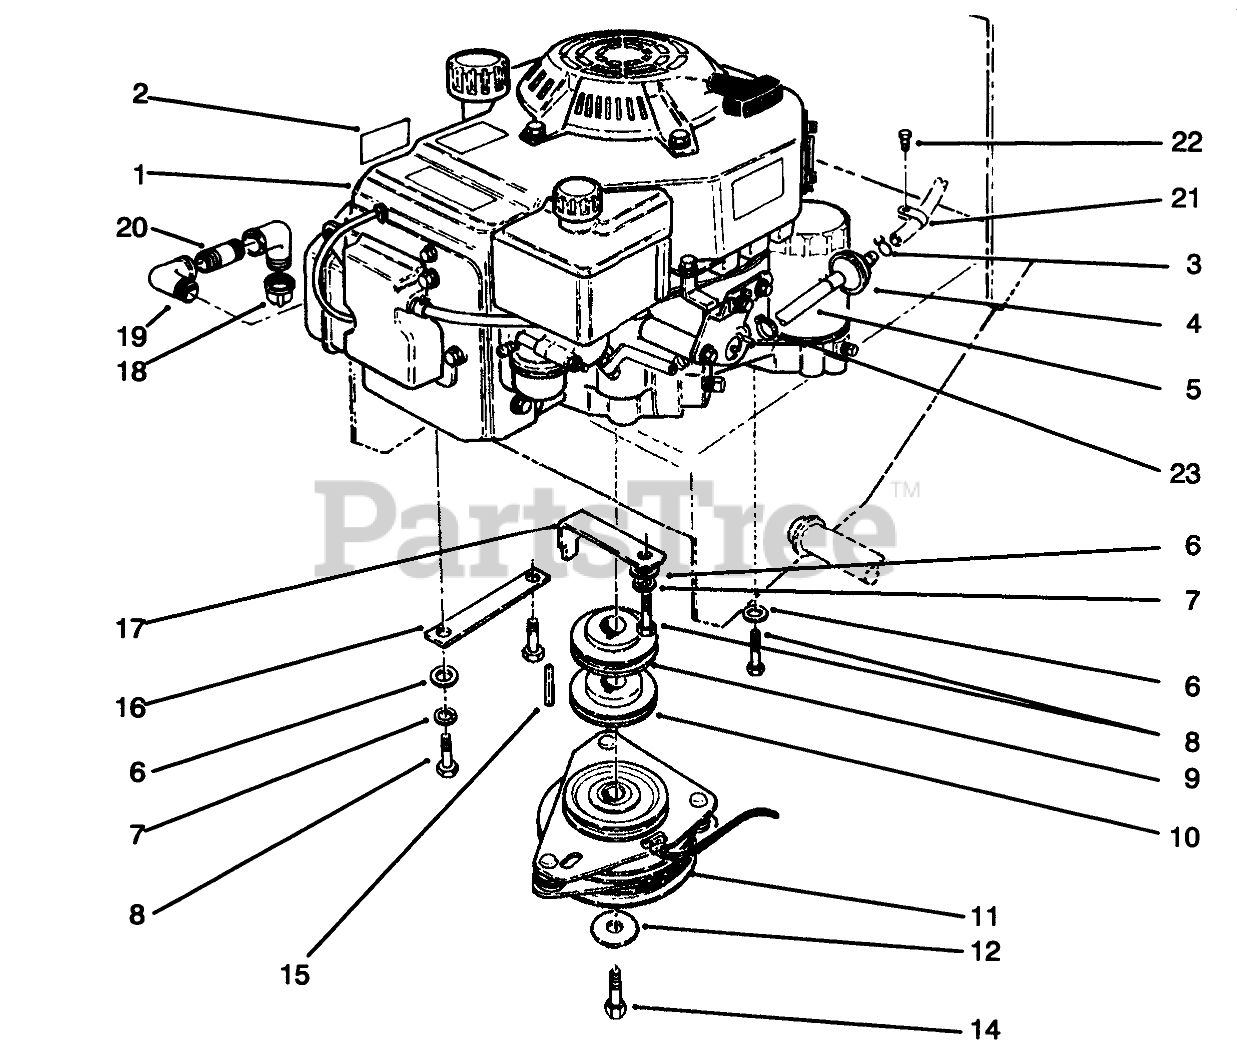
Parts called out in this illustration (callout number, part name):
2	DECAL-SURFACE, HOT
3	CLAMP-HOSE
4	FILTER-FUEL
5	HOSE-FUEL
6	WASHER-PLAIN
7	WASHER-LOCK
8	SCREW-HH
9	SHEAVE-UPPER HALF
10	SHEAVE-LOWER HALF
11	CLUTCH/BRAKE
12	WASHER-CLUTCH
14	SCREW-CLUTCH
15	KEY-SQUARE
16	Guard-Pulley
17	Retainer-Clutch
18	CAP-PIPE
19	ELBOW-STREET, 90 DEG
20	NIPPLE
21	CLAMP-CABLE
22	SCREW-SHWH
23	CLAMP-WORM
